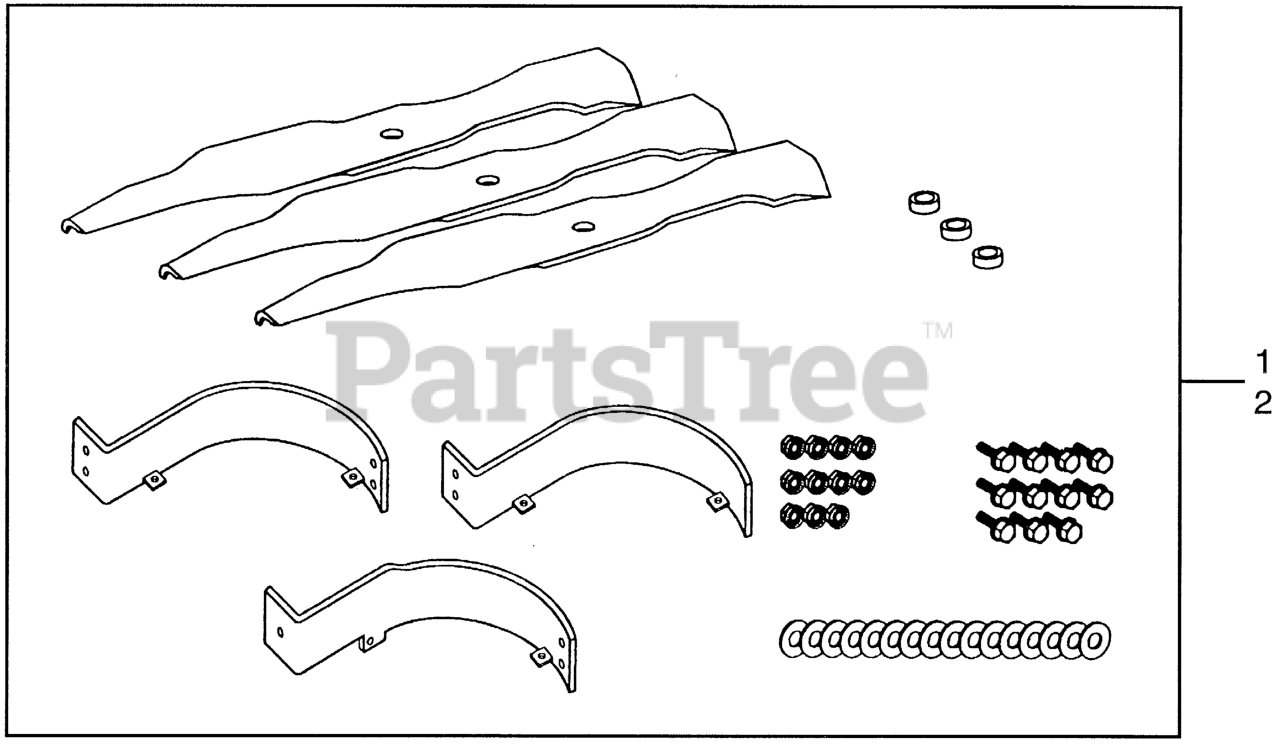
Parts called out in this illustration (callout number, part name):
1	MULCH KIT (52")
2	MULCH KIT (60")
NI	CATCHER, GRASS (LESS BAG)
